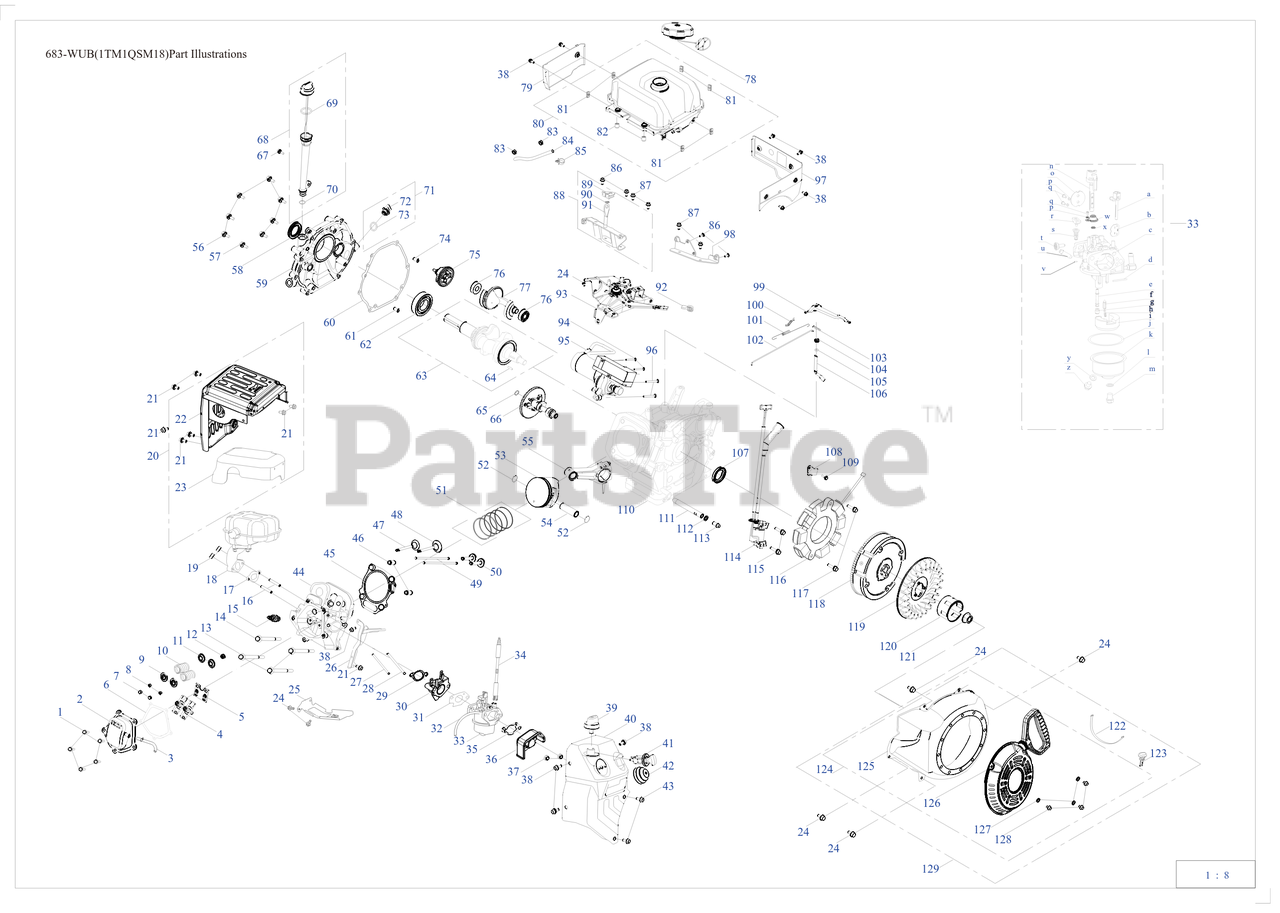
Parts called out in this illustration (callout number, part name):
1	BOLT M6 x 16
2	VALVE COVER
3	BREATHER HOSE
4	ROCKER ARM ASSEMBLY
5	PUSH ROD GUIDE
6	VALVE COVER GASKET
7	EXHAUST VALVE ADJUSTER
8	VALVE CAP
9	VALVE SPRING SEAT
10	VALVE SPRING
11	VALVE SPRING RETAINER
12	INTAKE VALVE SEAL
13	SCREW M10-1.25 x 87 x GR10.9
14	SCREW M10-1.25 x 65 x GR10.9
15	SPARK PLUG
16	STUDS M8-1.25 x 48.5
17	MUFFLER GASKET
18	MUFFLER
20	MUFFLER SHIELD ASSEMBLY
21	BOLT M6-1 x 10 GR8.8
22	Muffler Shroud
23	Muffler Inner Shield
24	BOLT M6-1 x 12 GR8.8
25	CYLINDER BAFFLE
26	RECOIL SNOW GUARD
28	STUD
29	CARBURETOR INSULATOR GASKET
30	Insulator
31	CARBURETOR INSULATOR GASKET
32	PRIMER HOSE
33	CARBURETOR
34	CHOKE KNOB SHAFT
35	HEATER BOX CARBURETOR GASKET
36	Heater Box
38	BOLT M6-1 x 14 GR8.8
39	CHOKE LEVER
40	CONTROL PANEL
41	ENGINE KEY SWITCH ASSEMBLY
43	SCREW M6-1 x 20 CL5.8
44	Cylinder Head
45	CYLINDER HEAD GASKET
47	EXHAUST VALVE
48	INTAKE VALVE
49	PUSH ROD
50	TAPPET
51	PISTON RING KIT
52	PISTON PIN SNAP RING
54	PISTON PIN
55	CONNECTING ROD ASSEMBLY
56	SCREW M8-1.25 x 38 GR10.9
57	BOLT M8 x 45
58	OIL SEAL
59	CRANKCASE COVER
60	CRANKCASE COVER GASKET
62	BALL BEARING
63	CRANKSHAFT ASSEMBLY
64	FLYWHEEL KEY
66	ENGINE CAMSHAFT ASSEMBLY
67	BOLT M6-1 x 18 GR8.8
68	OIL DIPSTICK ASSEMBLY
69	DIPSTICK O-RING
71	OIL DRAIN PLUG ASSEMBLY
72	Oil Plug
74	DOWEL PIN
75	GOVERNOR GEAR/SHAFT ASSEMBLY
76	BALL BEARING
77	BALANCE GEAR ASSEMBLY
79	FUEL TANK BACK PANEL
80	FUEL TANK ASSEMBLY
81	THREADED TAB
83	HOSE CLAMP
85	FUEL LINE SUPPORT CLAMP
87	BOLT M8-1.25 x 14 GR8.8
88	FUEL TANK MOUNTING BRACKET
89	RUBBER GROMMET
90	RUBBER GROMMET
91	FUEL TANK MOUNTING BRACKET
92	THROTTLE KNOB
93	THROTTLE CONTROL ASSEMBLY
95	ELECTRIC STARTER
96	BOLT M8-1.25 x 55 GR8.8
97	FUEL TANK FRONT PANEL
98	FUEL TANK BASE BRACKET
99	GOVERNOR ARM ASSEMBLY
100	GOVERNOR SPRING
101	IDLE SPRING
102	GOVERNOR ROD
103	GOVERNOR SHAFT CLIP
104	GOVERNOR SEAL
105	FLAT WASHER
106	GOVERNOR SHAFT
107	OIL SEAL
108	ALTERNATOR WIRE CLAMP BRACKET
109	BOLT M6-1 x 8 GR8.8
110	CRANKCASE COMPLETE
111	OIL DRAIN PIPE
112	WASHER
113	OIL DRAIN PLUG
114	IGNITION MODULE
115	IGNITION COIL BOLT M6-1 x 28 GR8.8
116	ALTERNATOR
117	BOLT-M6-1 x 30 GR8.8
119	COOLING FAN
120	STARTER CUP
121	FLYWHEEL NUT M16X1.5
122	CABLE TIE - 3 x 150
123	IGNITION KEY
124	BLOWER HOUSING ASSEMBLY
125	BLOWER HOUSING
126	RECOIL ASSEMBLY
127	RECOIL FLAT WASHER
128	BOLT M6 x 10
129	Recoil Starter
